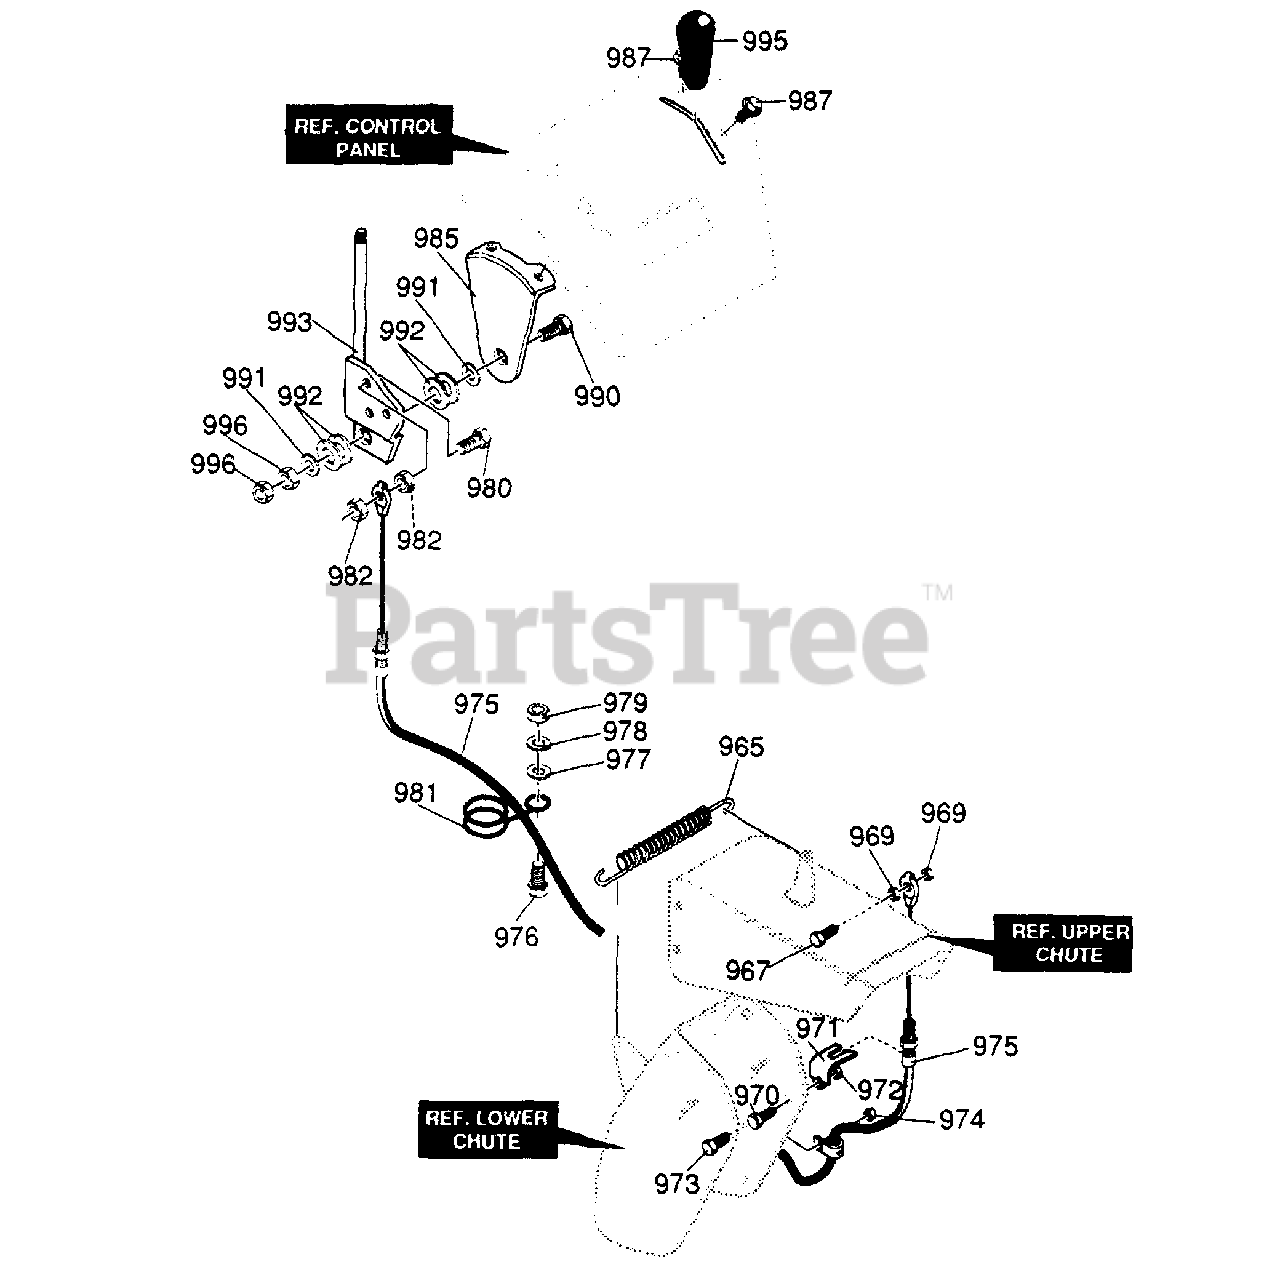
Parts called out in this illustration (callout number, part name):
965	SPRING, TENSION
967	SCREW 1/4-20X1.00 IN.
969	NUT, 1/4-20 REGHEXCTRLK
970	SCREW 5/16-18X.50
971	BRACKET, CABLE CHUTE
972	NUT, 5/16-18 REGHEXCTRLK
973	SCREW 10-24X.38 SLHWATAP
974	NUT #10-24 HEXNYLLK
975	CABLE, CHUTE CONTROL 52"
976	SCREW 5/16-18 X .75 IN.
977	FLATWASHER.344X.69X.065
978	WASHER HVSPTLK
979	NUT 5/16-18 REGHEX
980	SCREW 1/4-20 X 1.00
981	WIRE, FORM REMOTE CABLE
982	NUT, 1/4-20 REGHEXCTRLK
985	BRACKET, CABLE CHUTE
987	SCREW 5/16-18X.50 IN.
990	SCREW 3/8-16X1.75 IN.
991	FLATWASHER .406X.81 X.066
992	WASHER SPRING
993	HANDLE, ASSY SPEED CONTROL
995	HANDLE, 3/8-16
996	NUT, 3/8-16 HEXNYL
